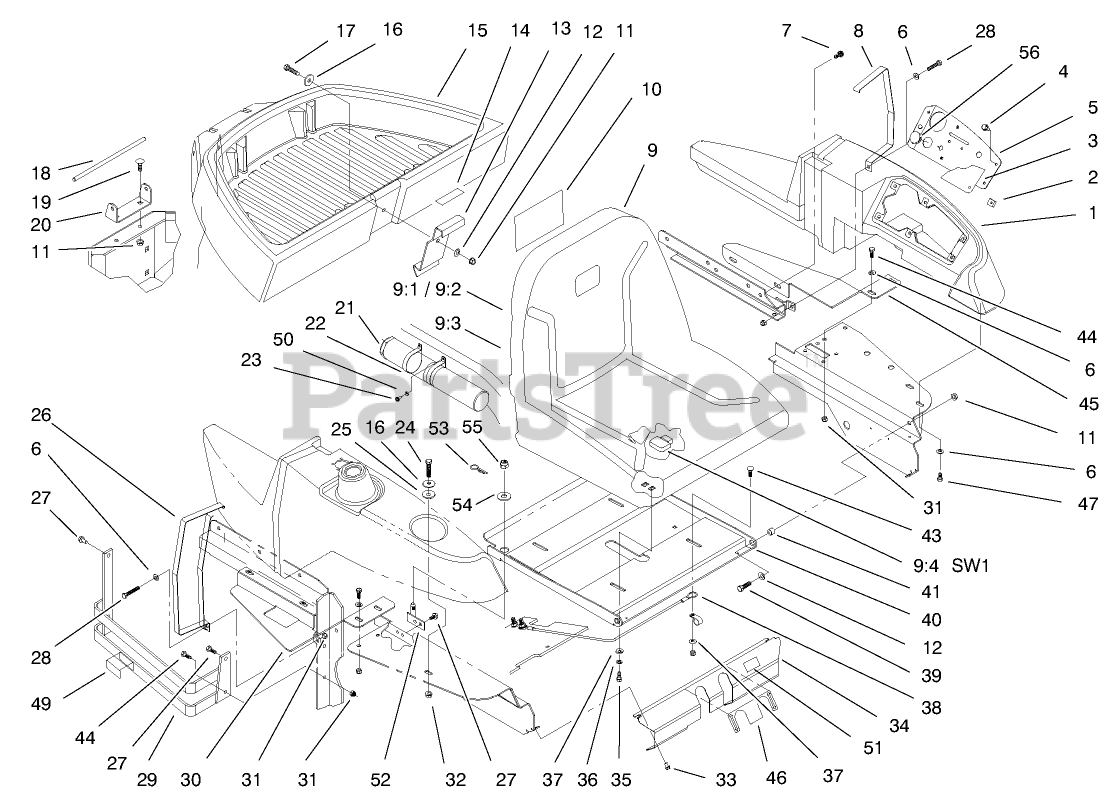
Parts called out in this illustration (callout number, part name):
1	CONSOLE
2	CLIP-TINNERMAN
3	DECAL - INSTRUMENT
4	SCREW-PPH
5	PANEL - INSTRUMENT
6	WASHER-PLAIN
7	SCREW-HWHTF
8	STRAP-CONSOLE
9	SEAT ASM
9:1	SHELL
9:2	SEAT CUSHION KIT
9:3	EDGING
9:4	SWITCH-SEAT
10	DECAL
11	NUT-LOCK, NI
12	WASHER-FLAT
13	LATCH - UTILITY BOX B
14	DECAL - NO RIDERS
15	BOX - UTILITY
16	WASHER
17	SCREW-HH
18	PIN - PIVOT,UTILITY BOX
19	BOLT-CARR
20	HINGE - DUMPBOX B
21	TUBE-MANUAL
22	CLAMP-R
23	RIVET-BLIND
24	SCREW-HH
25	BUSHING-FLANGE
26	STRAP-TANK, FUEL
27	SCREW-HWHTF
28	SCREW-HH
29	BUMPER ASM
30	PLATE-SUPPORT, TANK
31	NUT-LOCK, NI
32	NUT-HHF, WHIZ
33	SCREW-HWH
34	PLATE - COVER, FRONT
35	SCREW-HH
36	WASHER-LOCK
37	WASHER-FLAT
38	CABLE-SEAT
39	SCREW-HH
40	SEAT PLATE ASM
41	SPACER-WHEEL
43	BOLT-CARR
44	SCREW-HH
45	PLATE - CONSOLE SUPT R
46	DECAL - OPERATION
47	SCREW-HH
49	DECAL-HOT SURFACE
50	WASHER-FLAT
51	DECAL-PROTECTION, EAR
52	LATCH ASM
53	PIN-HAIR
54	WASHER-FLAT
56	PLUG - DOME 1.125 DIA
